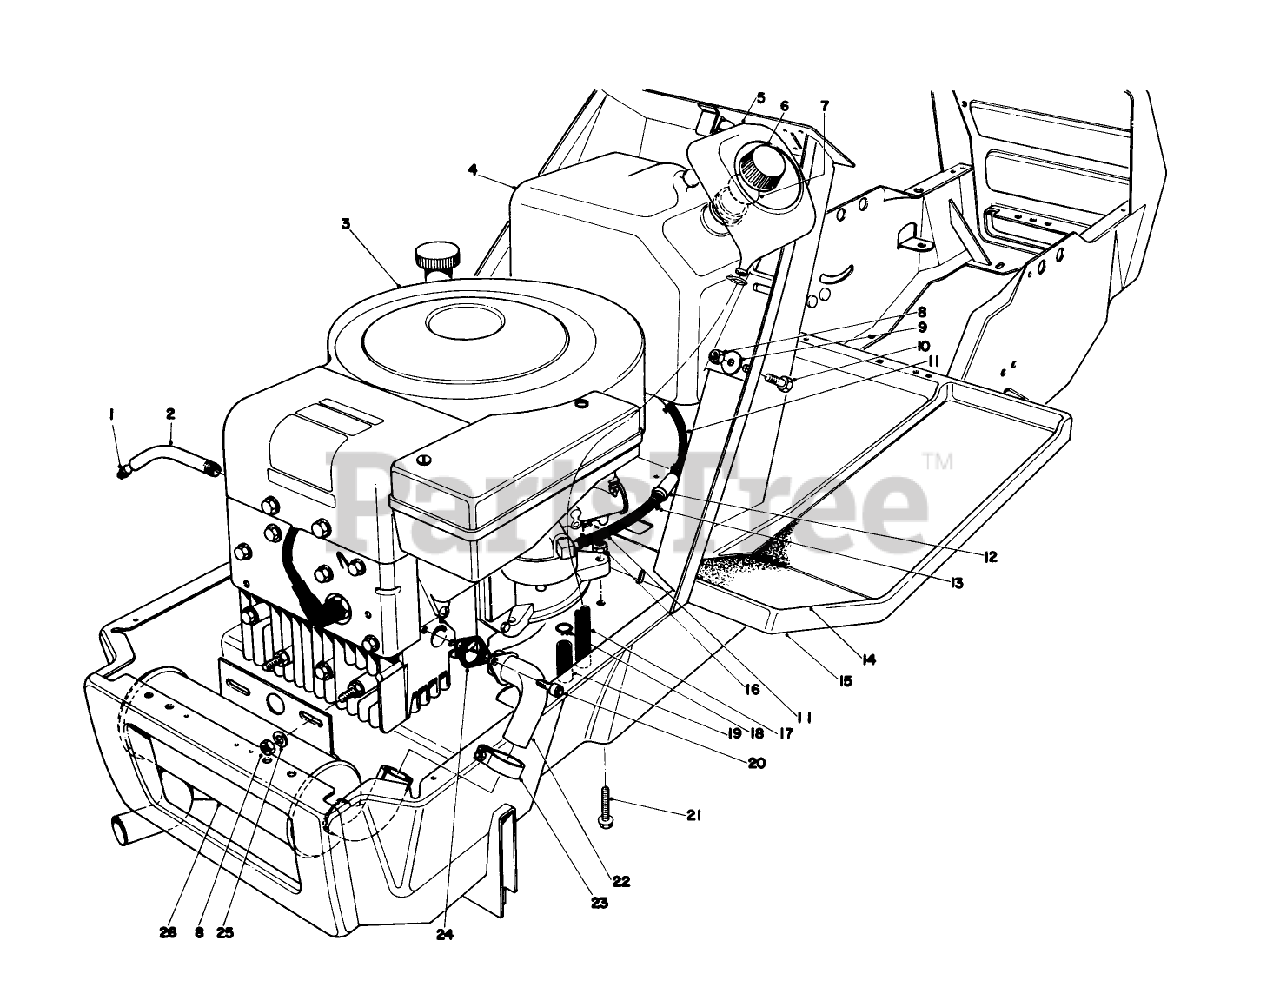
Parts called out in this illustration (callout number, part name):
1	PLUG-PIPE, SQH
3	Engine
8	NUT-LOCK, CONE
10	SCREW-HH
12	144 Gasket
16	NUT-LOCK, CONE
20	SCREW-HSH
21	SCREW-HH
24	Gasket Exhaust
25	WASHER-PLAIN
